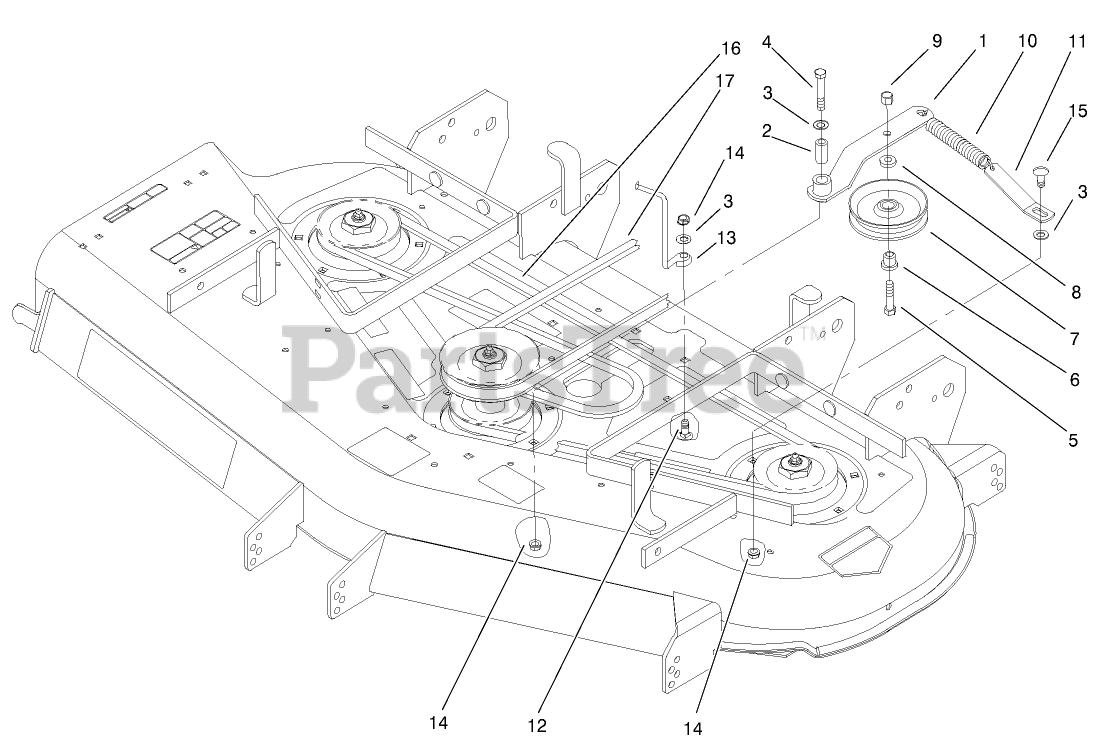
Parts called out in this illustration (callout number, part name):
1	IDLER ARM ASM
2	SLEEVE
3	WASHER-FLAT
4	SCREW-HH
5	SCREW-HH
6	BUSHING-PULLEY
7	PULLEY-IDLER
8	WASHER-FLAT
9	NUT-HEX
10	SPRING-EXTENSION
11	PLATE-SPRING
12	SCREW-CARR
13	GUIDE-BELT
14	NUT-HF
15	SCREW-CARR
16	V-BELT
17	BELT (52)
